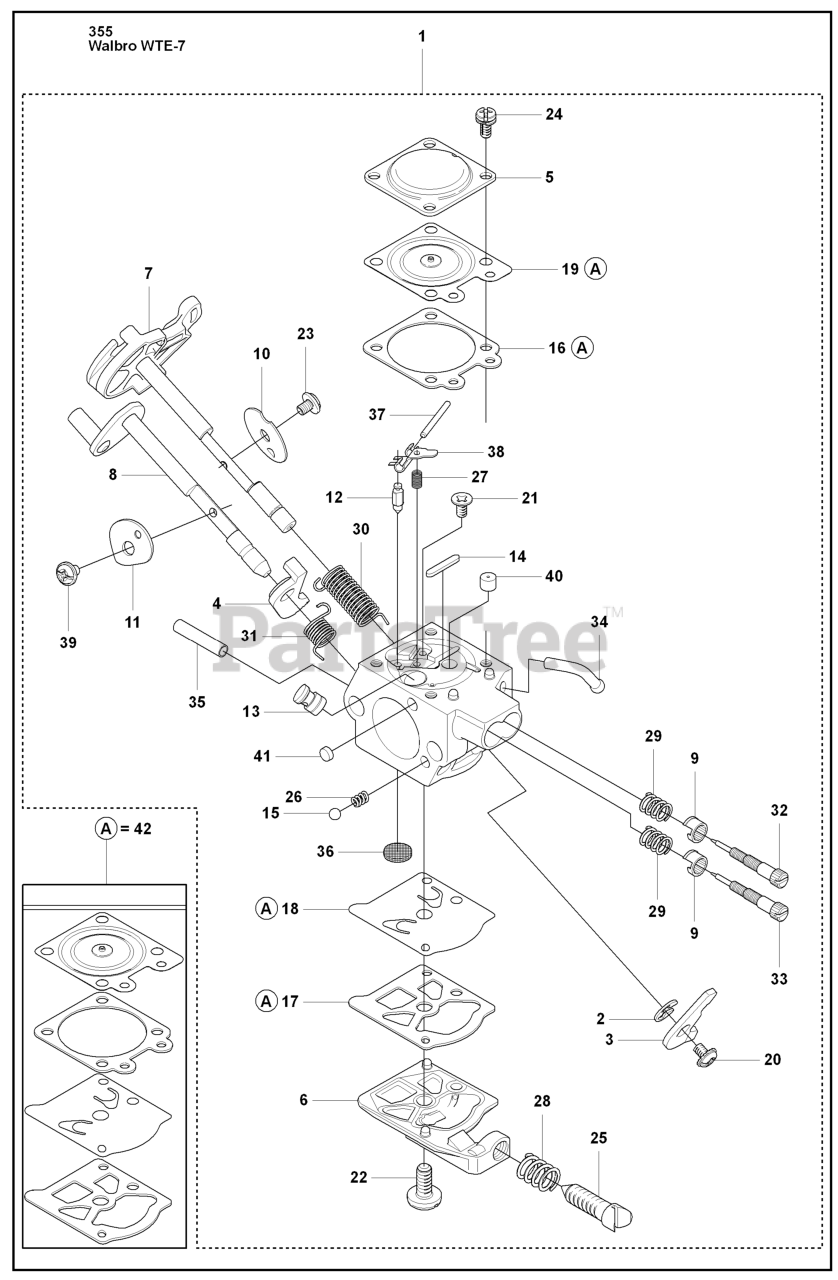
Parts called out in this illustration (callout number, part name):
1	CARBURETOR WTE-7-1
2	E CLIP
5	DIAPHRAGM COVER
9	LIMITER CAP
12	INLET NEEDLE
13	NOZZLE ASSY
18	DIAPHRAGM, FUEL PUMP
23	SCREW
24	RP SCREW W/ WASHER
28	SPRING
32	NEEDLE
33	NEEDLE
36	FUEL INLET SCREEN
37	FULCRUM PIN
41	PLUG WELCH
42	KIT
